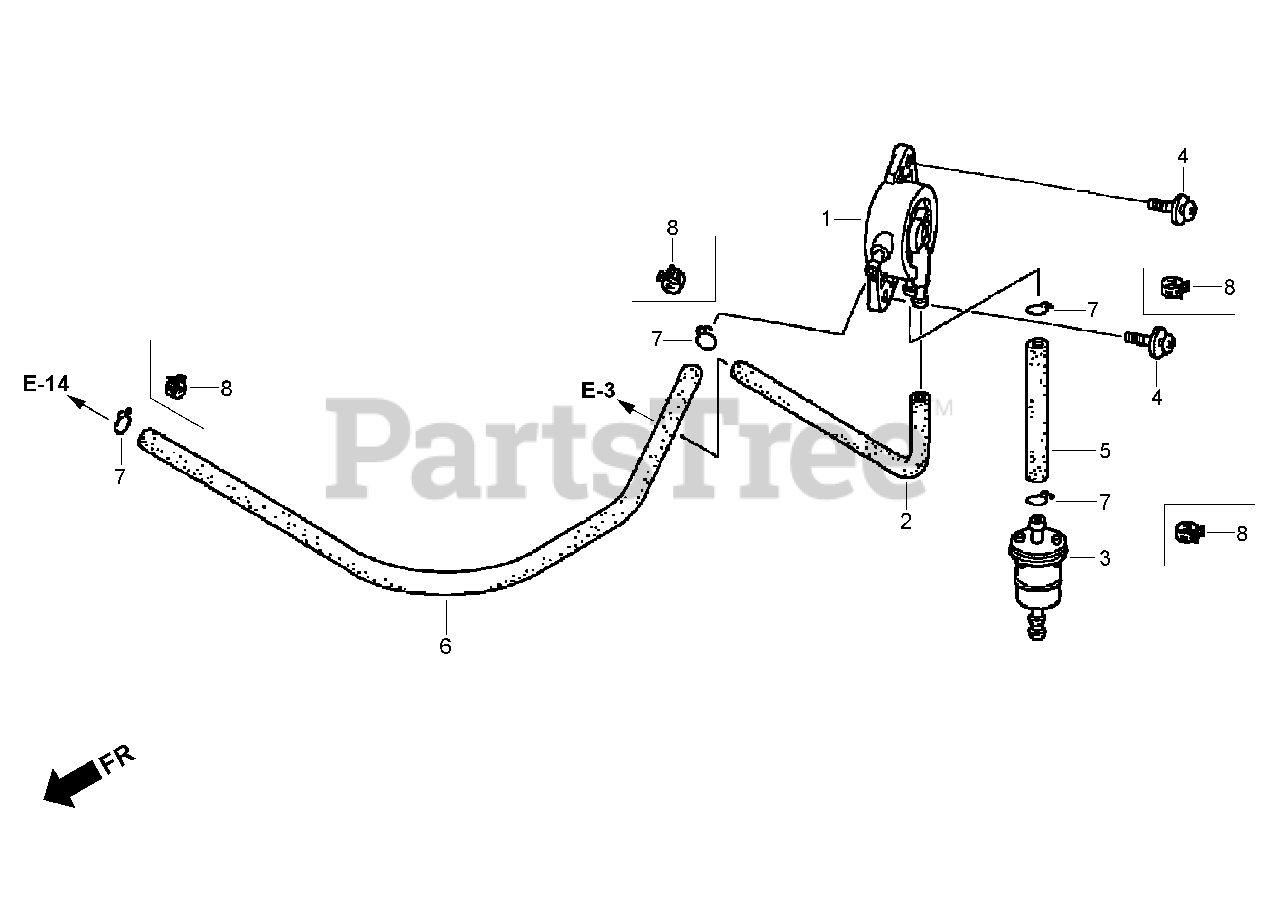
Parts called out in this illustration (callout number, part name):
1	FUEL PUMP ASM
2	TUBE-DIAPHRAGM
3	FILTER-FUEL
4	SCREW-WASHER (5X16)
5	TUBE-FUEL (5.3X100) (FKM) (From Engine Serial No. 1001842)
5	HOSE-FUEL, BULK (5.5X3000) (55X100) ( Up To Engine Serial No. 1001841)
6	TUBE-FUEL (5.3X350) (FKM) (From Engine Serial No. 1001842)
6	HOSE-FUEL, BULK (5.5X3000) (5.5X350) ( Up To Engine Serial No. 1001841)
7	CLIP-TUBE (B10) ( Up To Engine Serial No. 1001841)
8	CLAMP-TUBE (D10) (From Engine Serial No. 1001842)
